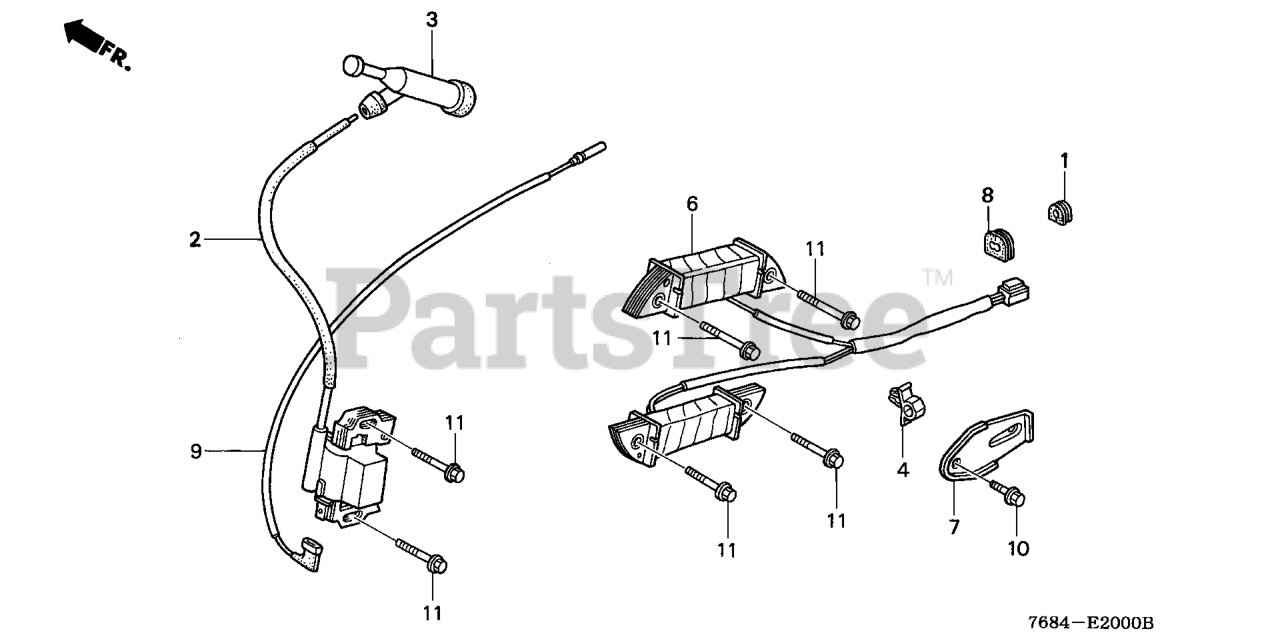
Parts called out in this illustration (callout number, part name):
1	GROMMET, OIL PIPE HOLDER
2	COIL ASSY., IGNITION
3	CAP ASSY., NOISE SUPPRESSOR (Honda Code 3526837). (NICHIWA Y-EZ RTFM256)
4	CLIP, IGNITION WIRE (8MM)
6	COIL ASSY., LAMP (12V/50W)
7	CLAMP, WIRE
8	GROMMET, WIRE
9	WIRE, STOP SWITCH (370MM)
10	BOLT, FLANGE (6X12) (CT200)
11	BOLT, FLANGE (6X28) (CT200) Use up to Engine SN 1530314.
